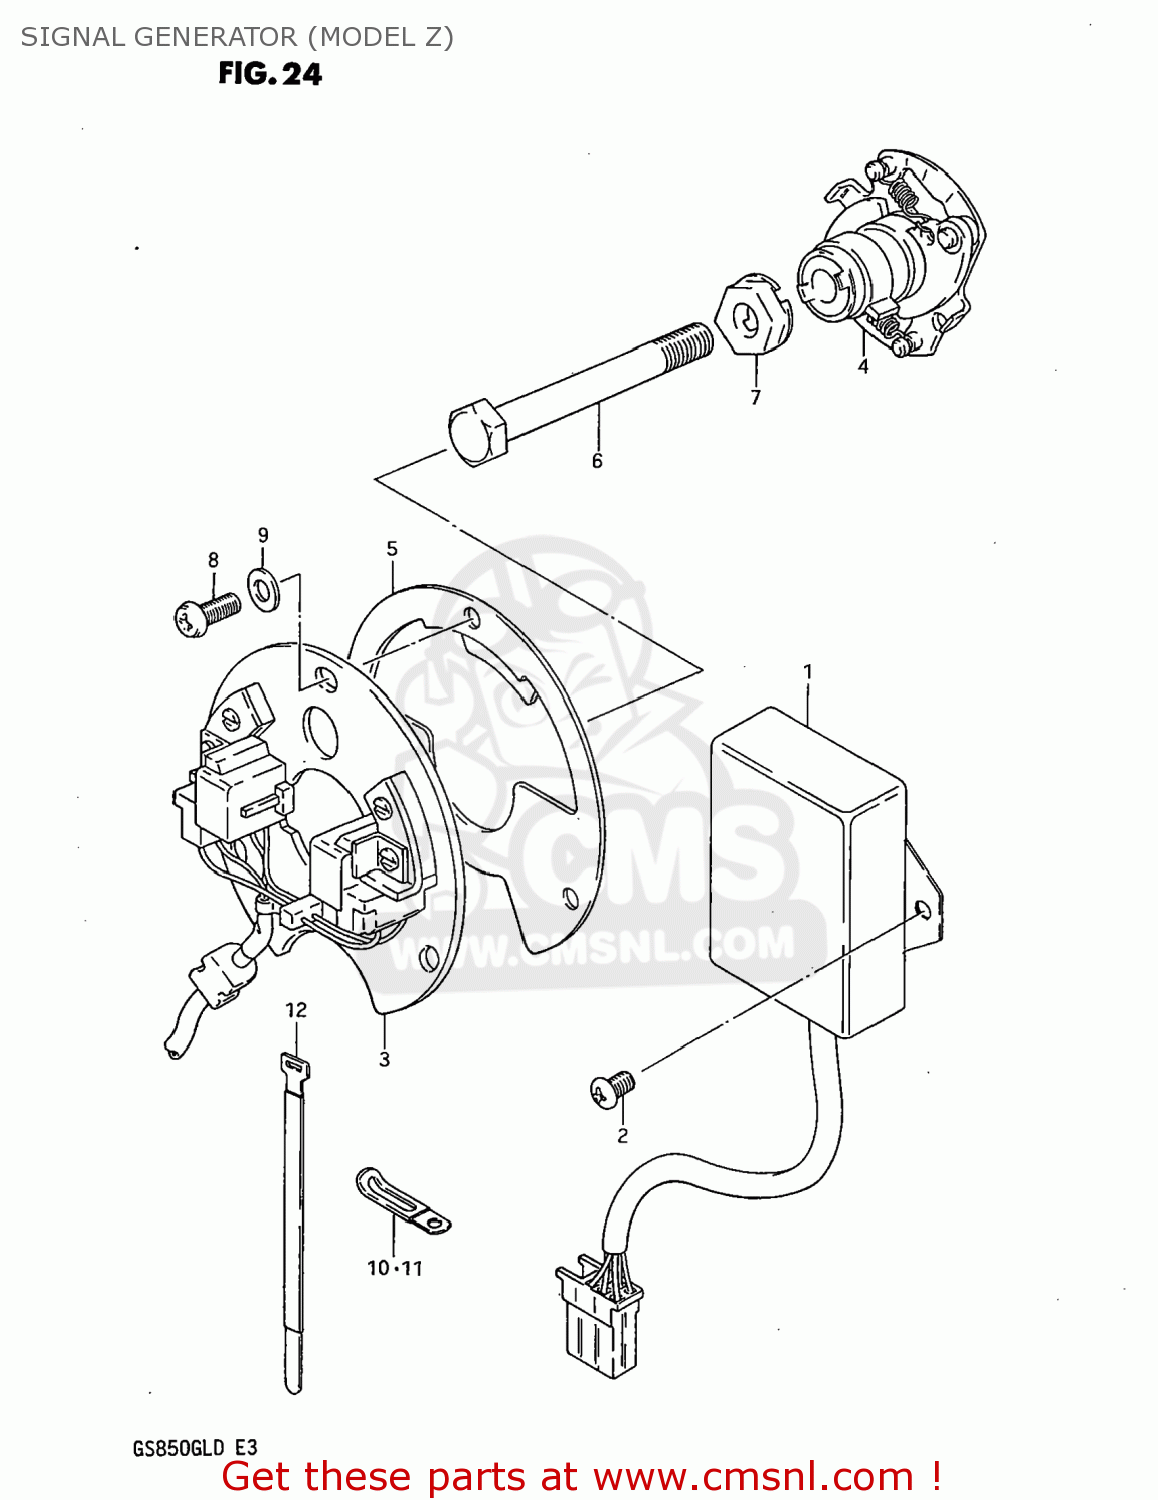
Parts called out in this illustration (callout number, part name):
1	IGNITER UNIT
2	SCREW
3	SIGNAL GENERATOR ASSEMBLY
4	GOVERNOR ASSEMBLY
5	PLATE,TIMING
6	BOLT
7	WASHER
8	SCREW(5X12)
9	WASHER
10	CLAMP L:35
11	CLAMP
12	CLAMP
